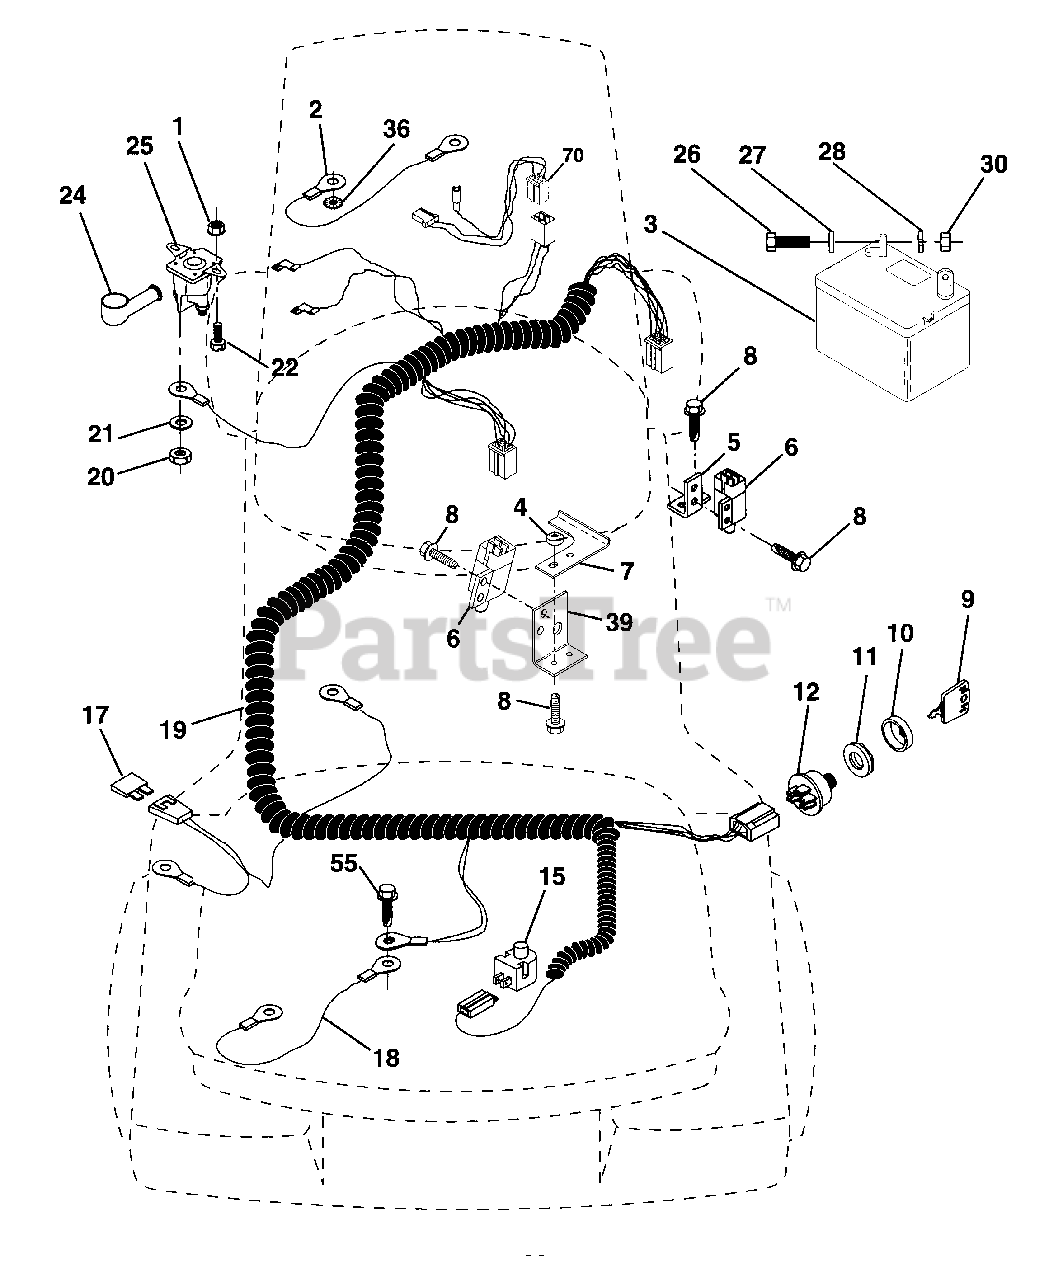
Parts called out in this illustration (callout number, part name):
1	Nut, Hex Keps 1/4-20
2	Assembly, Cable
3	Battery
4	Nut, Lock #10-24 UNC
5	Bracket, Switch
6	Switch, Interlock (4-terminal)
7	Keeper Actuator
8	Screw, Hex Hd. Tap #10-24 x 1/2
9	Key, Steel Delta
10	Cover, Key Ignition
11	Nut, Ignition
12	Switch, Ignition
15	Switch, Plunger
18	Assembly, Cable
19	Harness, Ignition
20	Nut, Hex Jam 1/4-20
21	Washer, Lock 1/4
22	Bolt, Fin. Hex 1/4-20 UNC x 1/2 Gr. 5
24	Cover, Terminal
25	Solenoid
26	Bolt, Hex Hd. 1/4-20 UNC x 3/4
27	Washer 9/32 x 5/8 x 16
28	Washer, Lock 1/4
30	Nut, Fin. Hex 1/4-20 UNC
36	Washer, Lock Inter. Tooth 1/4
39	Bracket, Switch Clutch
55	Screw Thdrol 5/16-18 x 1/2
70	Harness, Engine
